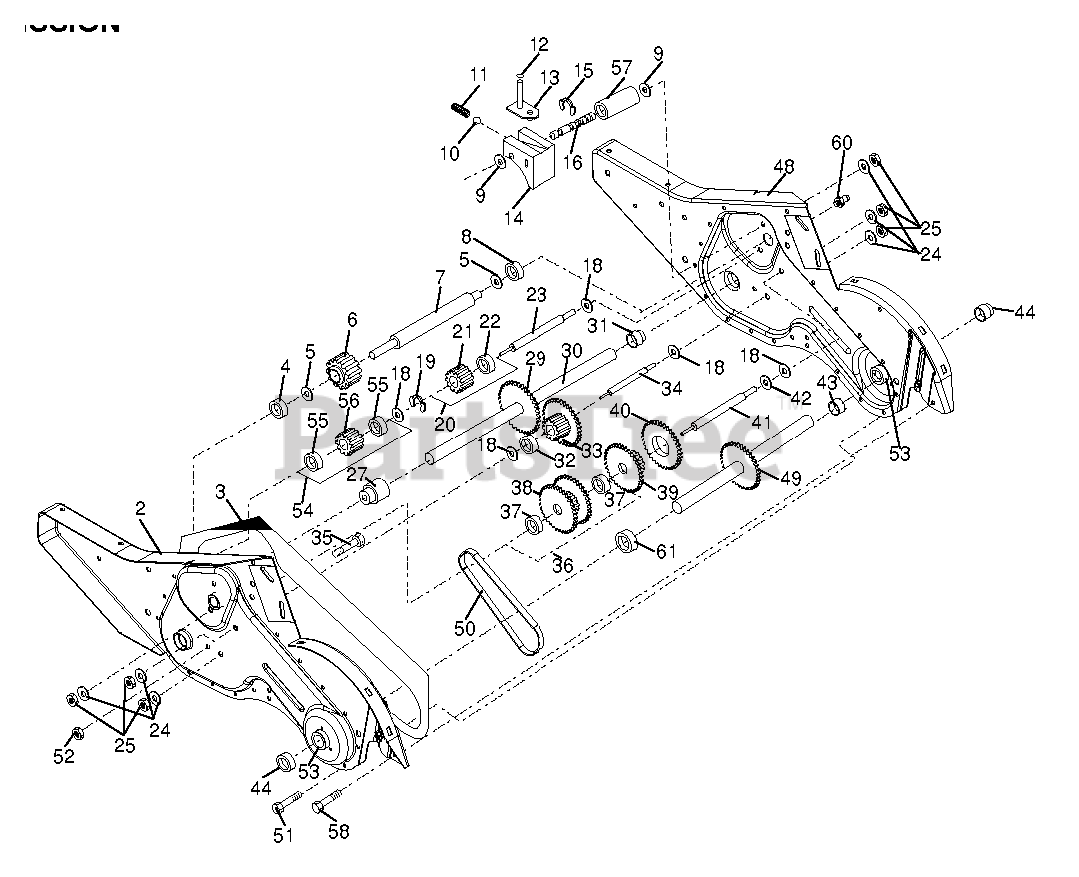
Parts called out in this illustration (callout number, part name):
2	GEARCASE.ASM.DRT.LH.
3	GASKET.GEARCASE.CRT/DRT.TILLER
4	NEEDLE BRNG LT
5	THRUST WASHER
6	GEAR.PINION.INPUT.DRT
7	SHAFT.INPUT.D.9TEETH
9	WASHER, SEAL (2 2)
10	BALL, STEEL
11	SPRING-SHIFT CRT
13	BRACKET ASM.SHIFT.CRT
14	SHIFT FORK TI
16	SHAFT.SHIFT.DRT
20	GEAR ASSY CRT
21	GEAR-REV IDLR CRT
22	NEEDLE BEARING TI
23	SHAFT.IDLER.REVERSE.CRT
24	LOCKWASHER
25	NUT.ASF.HEX.7/16
27	BEARING.GROUND.DRIVE
30	GROUND SHAFT ASS'Y
31	BEARING, SHAFT RH CRT
33	SPRCKT 8 GEAR CRT
34	SHAFT.SECONDARY.REDUCTION.CRT
35	SCRW WHIZ LOK CRT
36	GEAR & SPROCKET.ASM.WBEARIN
37	BEARING.NEEDLE.CRT
38	ASM.GEAR & SPROCKET
39	GEAR.CLUSTER.DRT.TILLER
41	SHAFT.REDUCTION.FIRST.DRT
42	BRNG RACE T
44	SEAL ASM, OIL
48	GEARCASE.ASM.DRT.RH.
49	SHAFT.ASM.TINE
50	CHAIN.TILLER
51	SCREW
53	KIT.BEARING.TILLER.
54	GEAR.ASM.DRT.TILLER
55	BEARING.NEEDLE
56	GEAR.DRT.IDLER
57	SPACER.SPLIT
58	BOLT SHOULDER 1/4-20 UNC X.875
60	FITTING.GREASE.TAPERED
61	GREASE CARTRIDGE
61	SPACER.1.015X1.50X.650
